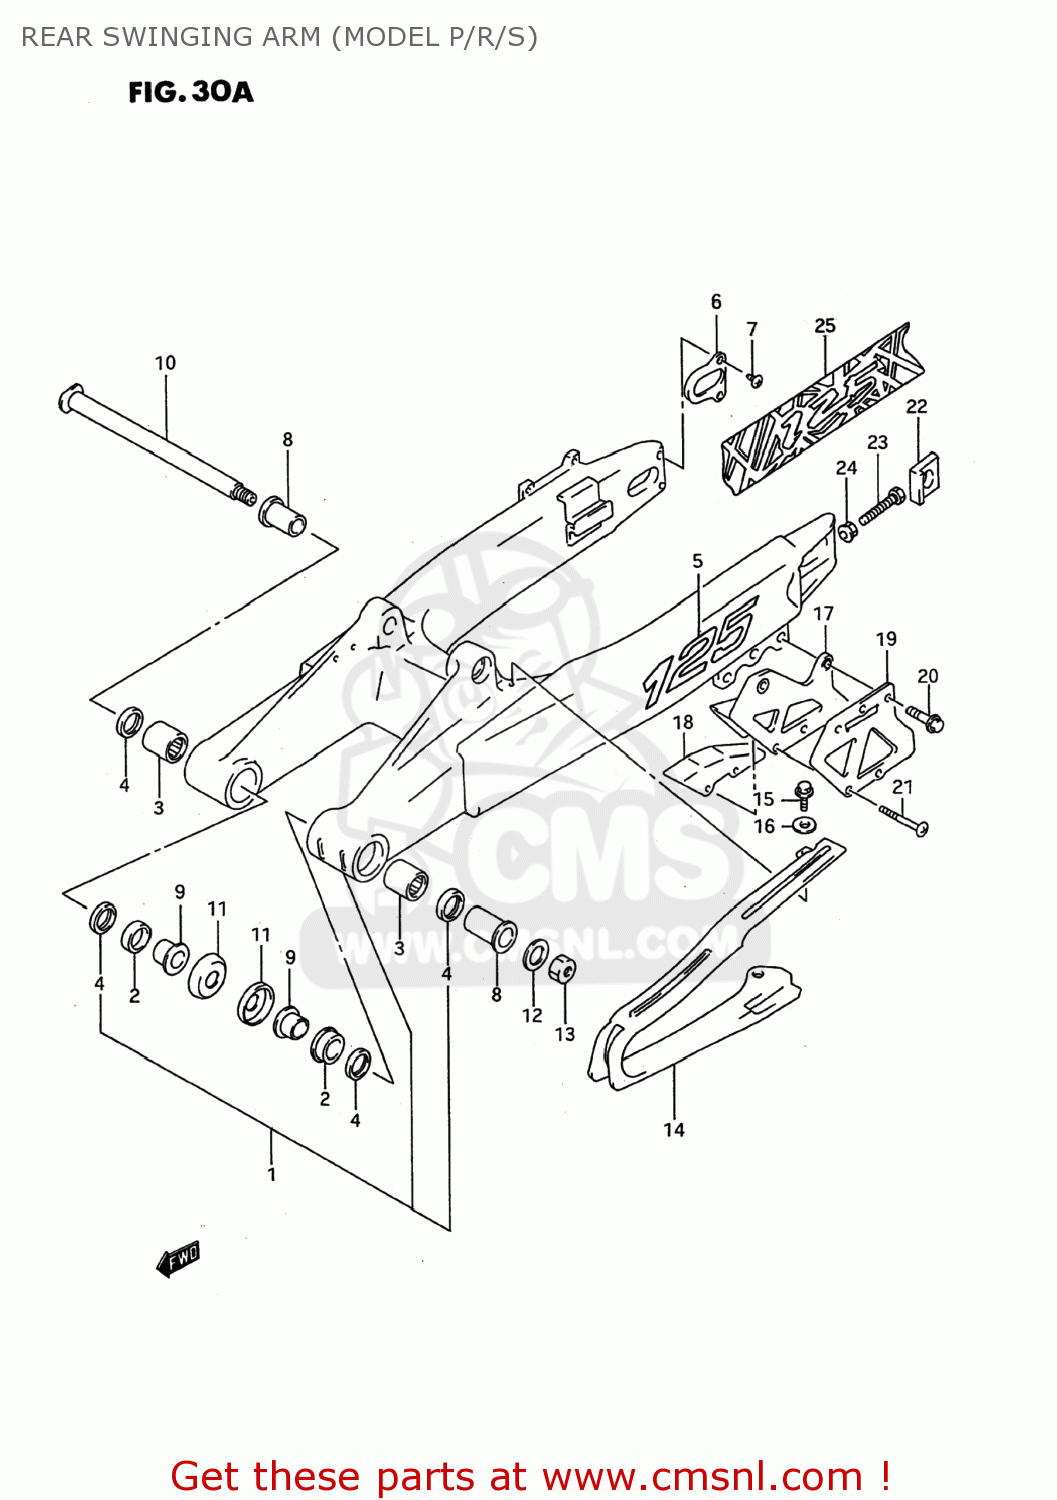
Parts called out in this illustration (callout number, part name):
1	SWING ARM ASSEMBLY,REAR
2	BUSHING,SWGARM PIVOT
3	BEARING(22X29X30)
4	SEAL,OIL(22X29X4)
5	EMBLEM,SWING ARM
6	PLATE,SWING ARM,REAR
7	SCREW(5X8)
8	SPACER,REAR SWING ARM
9	SPACER,SWGARM PIVOT INNER
10	SHAFT,RR SWINGINGARM PIVOT
11	COVER,SWINGINGARM PIVOT
12	WASHER
13	NUT
14	BUFFER,CHAIN TOUCH DEFENSE
15	BOLT
16	WASHER
17	GUIDE,CHAIN
18	DEFENSE,CHAIN GUIDE
19	PLATE,CHAIN GUIDE OUTER
20	BOLT
21	SCREW(6X40)
22	WASHER,CHAIN ADJUSTER
23	BOLT(8X50)
24	NUT
25	EMBLEM,SWING ARM
